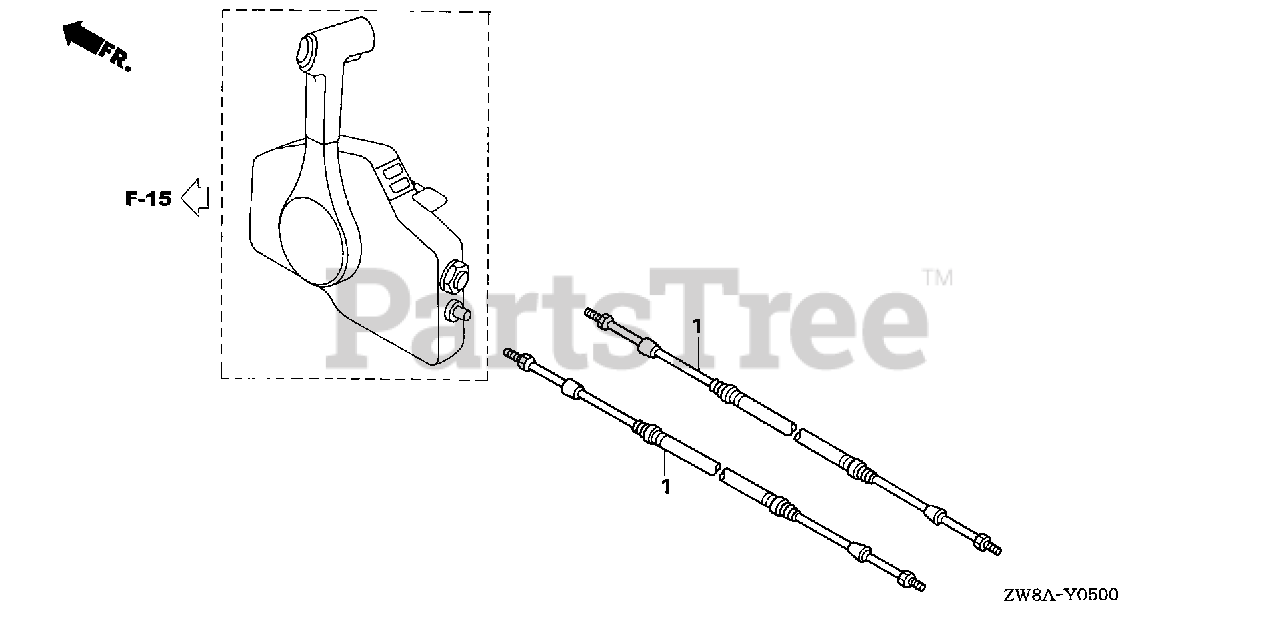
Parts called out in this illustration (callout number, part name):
1	CABLE, REMOTE CONTROL (10') (LOW FRICTION)
1	CABLE ASSY., PUSH-PULL (33C-5FT)
1	CABLE, REMOTE CONTROL (11') (LOW FRICTION)
1	CABLE ASSY., PUSH-PULL (33C-6FT)
1	CABLE, REMOTE CONTROL (12') (LOW FRICTION)
1	CABLE ASSY., PUSH-PULL (33C-7FT)
1	CABLE, REMOTE CONTROL (13') (LOW FRICTION)
1	CABLE ASSY., PUSH-PULL (33C-8FT)
1	CABLE, REMOTE CONTROL (14') (LOW FRICTION)
1	CABLE ASSY., PUSH-PULL (33C-9FT)
1	CABLE, REMOTE CONTROL (15') (LOW FRICTION)
1	CABLE ASSY., PUSH-PULL (33C-10FT)
1	CABLE, REMOTE CONTROL (16') (LOW FRICTION) (NOT AVAILABLE)
1	CABLE ASSY., PUSH-PULL (33C-11FT)
1	CABLE, REMOTE CONTROL (17') (LOW FRICTION)
1	CABLE ASSY., PUSH-PULL (33C-12FT)
1	CABLE, REMOTE CONTROL (18') (LOW FRICTION) (NOT AVAILABLE)
1	CABLE ASSY., PUSH-PULL (33C-13FT)
1	CABLE, REMOTE CONTROL (19') (LOW FRICTION)
1	CABLE ASSY., PUSH-PULL (33C-14FT)
1	CABLE, REMOTE CONTROL (20') (LOW FRICTION) (NOT AVAILABLE)
1	CABLE ASSY., PUSH-PULL (33C-15FT)
1	CABLE, REMOTE CONTROL (21') (LOW FRICTION)
1	CABLE ASSY., PUSH-PULL (33C-16FT)
1	CABLE, REMOTE CONTROL (22') (LOW FRICTION) (NOT AVAILABLE)
1	CABLE ASSY., PUSH-PULL (33C-17FT)
1	CABLE, REMOTE CONTROL (23') (LOW FRICTION)
1	CABLE ASSY., PUSH-PULL (33C-18FT)
1	CABLE, REMOTE CONTROL (24') (LOW FRICTION) (NOT AVAILABLE)
1	CABLE ASSY., PUSH-PULL (33C-19FT)
1	CABLE, REMOTE CONTROL (25') (LOW FRICTION)
1	CABLE ASSY., PUSH-PULL (33C-20FT)
1	CABLE, REMOTE CONTROL (26') (LOW FRICTION)
1	CABLE ASSY., PUSH-PULL (33C-21FT)
1	CABLE, REMOTE CONTROL (27') (LOW FRICTION)
1	CABLE ASSY., PUSH-PULL (33C-22FT)
1	CABLE, REMOTE CONTROL (28') (LOW FRICTION) (NOT AVAILABLE)
1	CABLE ASSY., PUSH-PULL (33C-23FT)
1	CABLE, REMOTE CONTROL (29') (LOW FRICTION)
1	CABLE ASSY., PUSH-PULL (33C-24FT)
1	CABLE, REMOTE CONTROL (30') (LOW FRICTION) (NOT AVAILABLE)
1	CABLE ASSY., PUSH-PULL (33C-25FT)
1	CABLE, REMOTE CONTROL (31') (LOW FRICTION)
1	CABLE ASSY., PUSH-PULL (33C-26FT)
1	CABLE, REMOTE CONTROL (32') (LOW FRICTION) (NOT AVAILABLE)
1	CABLE ASSY., PUSH-PULL (33C-27FT)
1	CABLE, REMOTE CONTROL (33') (LOW FRICTION)
1	CABLE ASSY., PUSH-PULL (33C-28FT)
1	CABLE, REMOTE CONTROL (34') (LOW FRICTION) (NOT AVAILABLE)
1	CABLE ASSY., PUSH-PULL (33C-29FT)
1	CABLE, REMOTE CONTROL (35') (LOW FRICTION)
1	CABLE ASSY., PUSH-PULL (33C-30FT)
1	CABLE ASSY., PUSH-PULL (33C-31FT)
1	CABLE ASSY., PUSH-PULL (33C-32FT)
